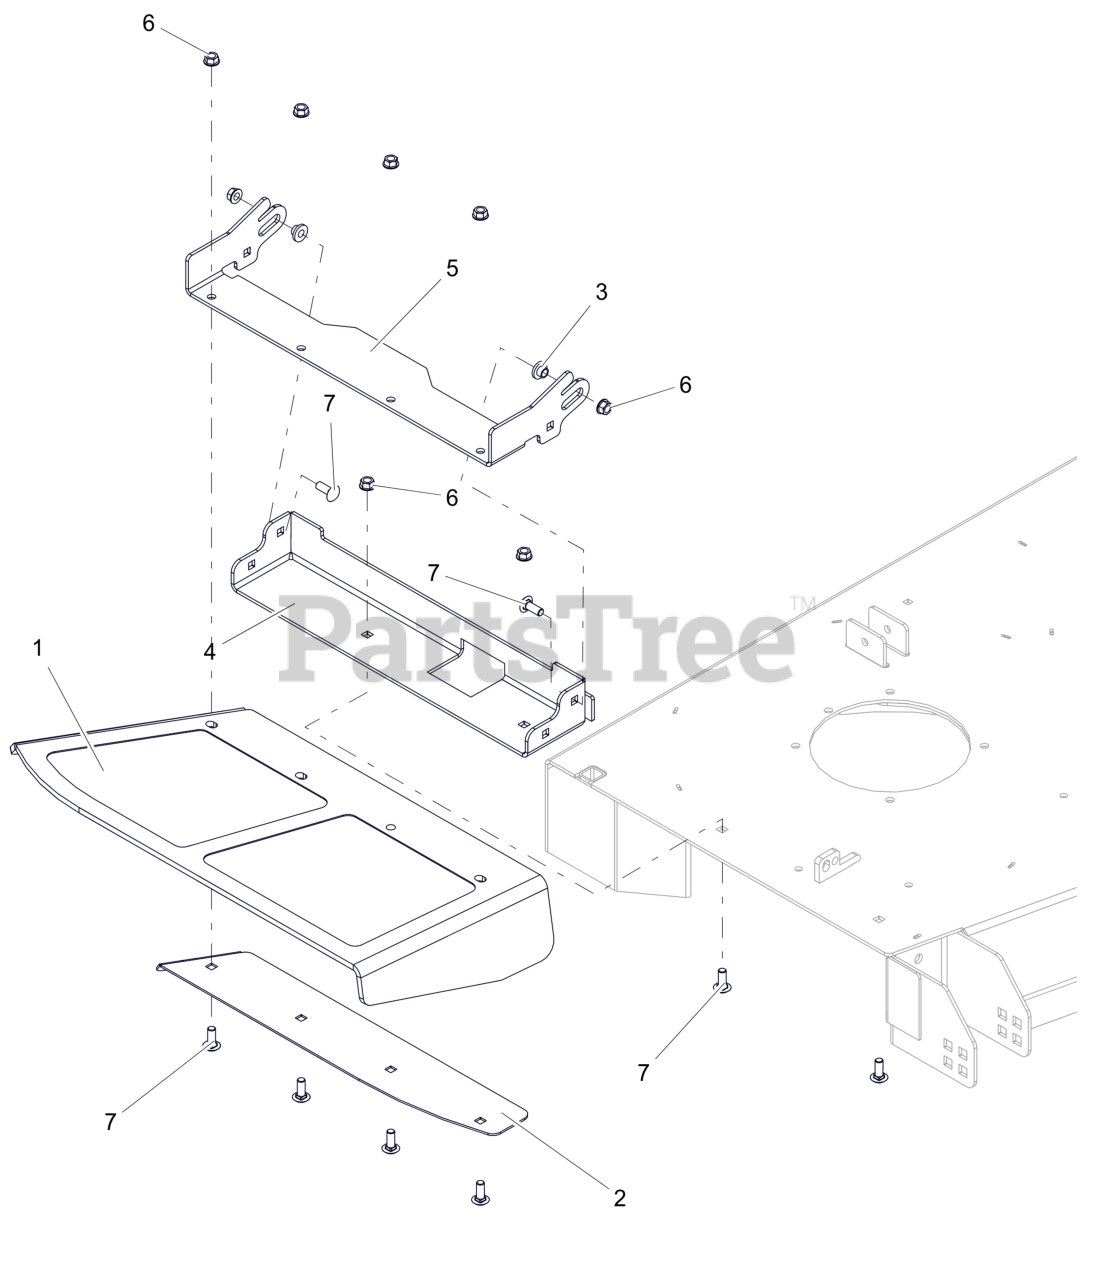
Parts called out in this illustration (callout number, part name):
1	CHUTE, 72" FORMED RUBBER DISCH
2	72" DISCH CHUTE CLAMP PLT -RED
3	BSHG-FLG .385X.500X.875X.406
4	BASE, DISCHARGE CHUTE MTG (RED) W/ SAFETY DECALS
5	BRKT, CHUTE MTG (RED)
6	NUT-LK-CTR-FLG .375-16 GF ZCC
7	BLT,RHSSN .38-16X1.00 G5 ZCC
